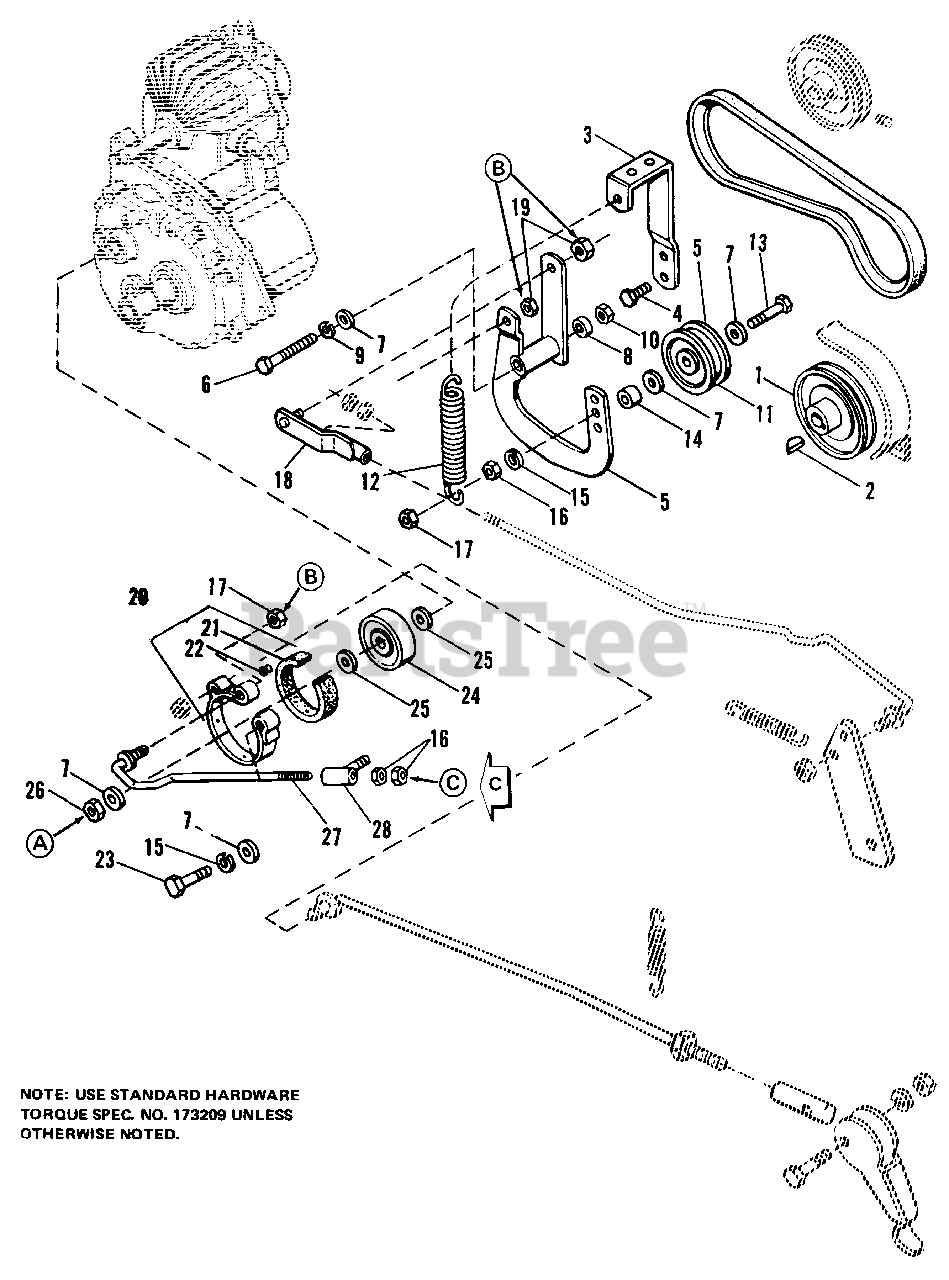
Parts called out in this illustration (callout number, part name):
1	PULLEY
2	KEY
4	SCREW, Thd. Form., 3/8 x 3/4
5	LEVER ASSY, Idler
6	CAPSCREW, Hex Hd., 7/16-14 x 3-3/4
7	WASHER, 3/8 Std.
9	LOCKWASHER, 7/16
10	NUT, Hex, Full, 7/16-14
11	PULLEY, Idler
13	CAPSCREW, Hex Ad, 3/8-16 x 2-1/4
15	LOCKWASHER, 3/8
16	NUT, Hex, Full, 3/8-16
17	NUT, Lock, Hex, 3/8-16
18	GUIDE ASSY
19	NUT, Lock, Hex, 5/16-18
20	BAND ASSY, Brake
21	LINING, Brake
23	CAPSCREW, Hex Hd., 3/8-16 x 1-3/4
24	DRUM, Brake
25	WASHER, Special
26	NUT, Lock, Hex, 7/16-14
28	GUIDE ASSY, Rod
